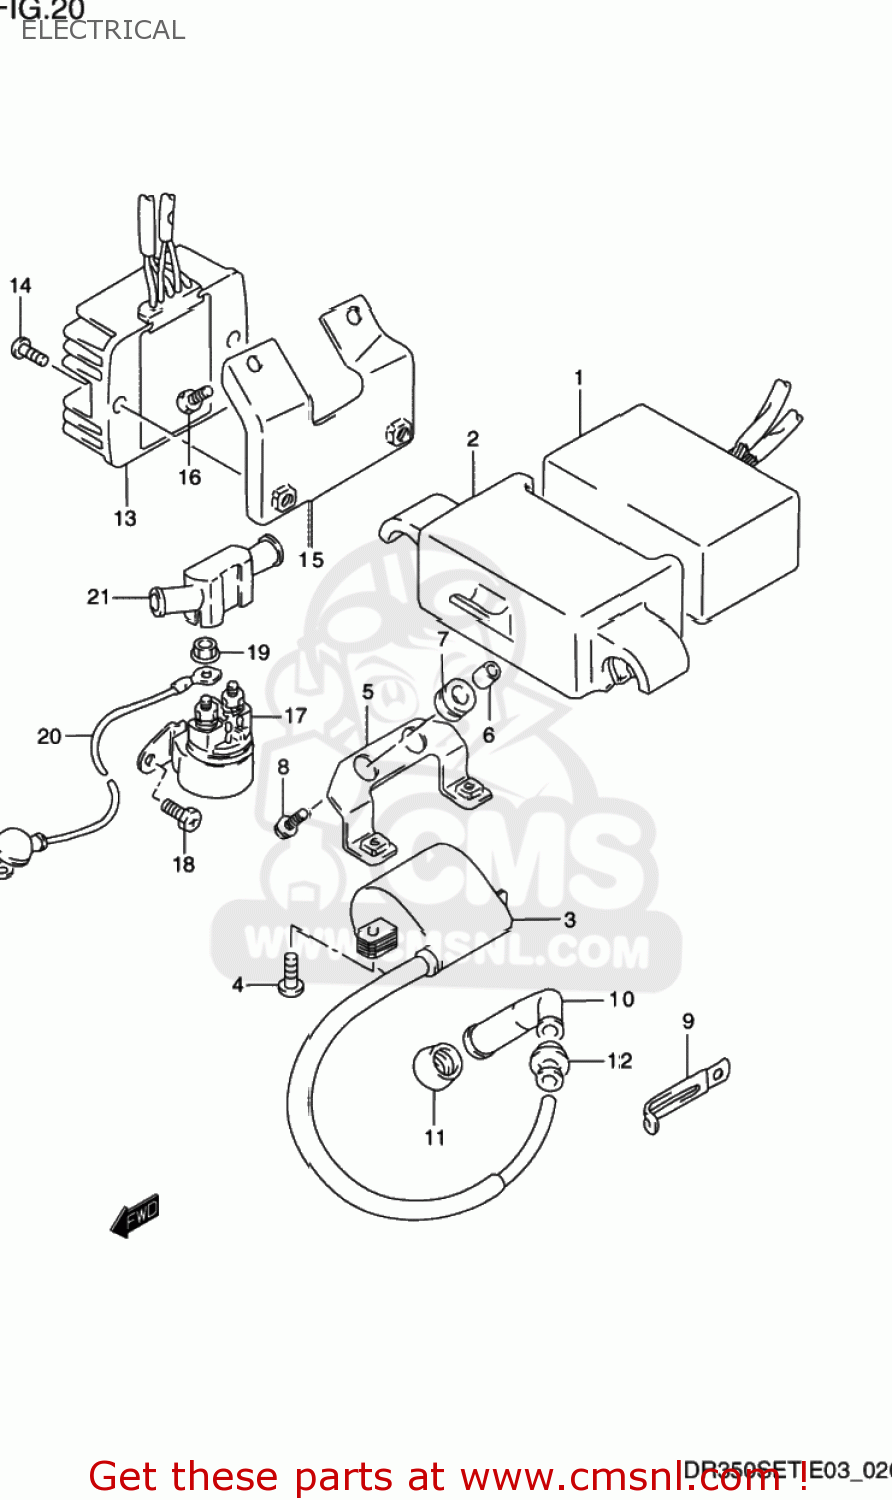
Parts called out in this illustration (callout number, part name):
1	CDI UNIT
2	CUSHION,CDI UNIT
3	COIL ASSY,IGNITION
4	SCREW
5	BRACKET,IGNITION COIL
6	SPACER (6.3X9.1X6.7)
7	CUSHION
8	BOLT
9	CLAMP
10	CAP,SPARK PLUG
11	SEAL,SPARK PLUG
12	SEAL,HIGH TENSION CORD
13	RECTIFIER ASSY
14	SCREW
15	BRACKET,RECTIFIER
16	BOLT
17	RELAY ASSY,STARTING MOTOR
18	SCREW(6X10)
19	NUT
20	WIRE,STARTER MOTOR
21	CAP,STARTER RELAY TERMINAL
